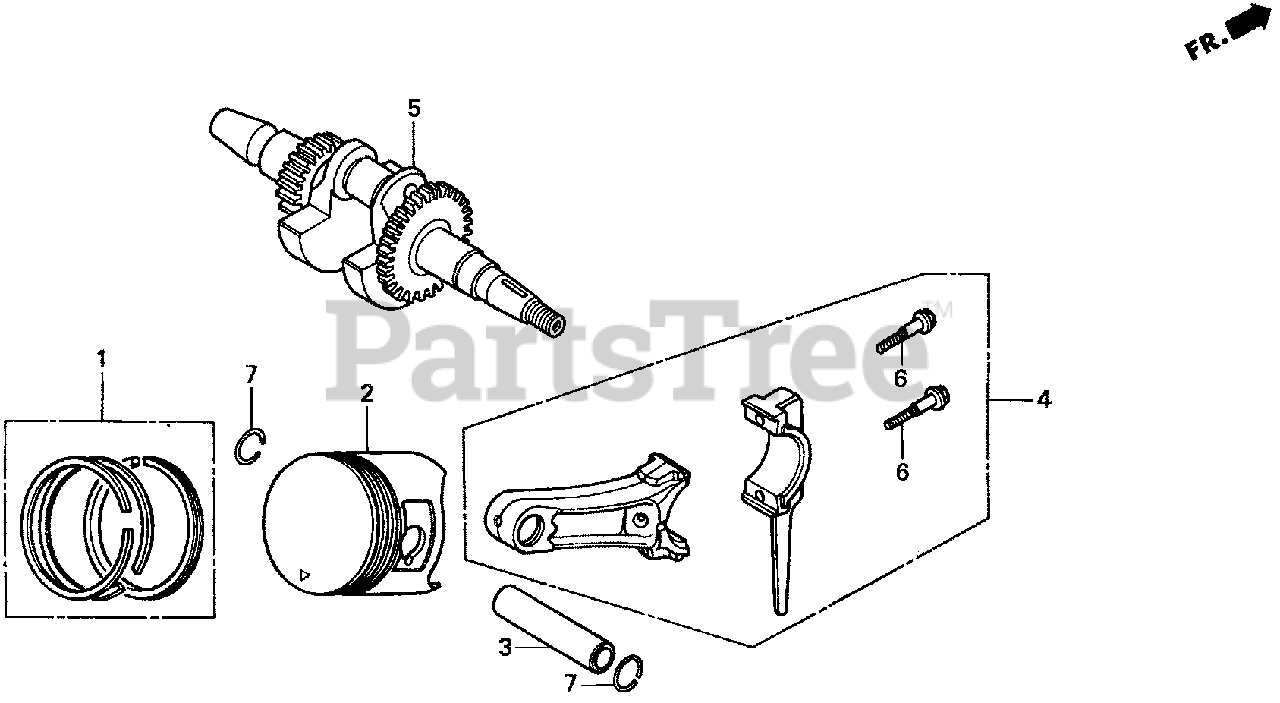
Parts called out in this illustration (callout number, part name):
1	RING SET, PISTON (STD)
1	RING SET, PISTON (STD) (TEIKOKU)
1	RING SET, PISTON (STD) (NIPPON)
1	RING SET, PISTON (OS 0.25) Use up to Engine SN 3993725.
1	RING SET, PISTON (OS 0.25) Use from Engine SN 3993726.
1	RING SET, PISTON (OS 0.50) Use up to Engine SN 3993725.
1	RING SET, PISTON (OS 0.50) Use from Engine SN 3993726.
1	RING SET, PISTON (0.75) Use up to Engine SN 3993725.
1	RING SET, PISTON (0.75) Use from Engine SN 3993726.
2	PISTON (STD)
2	PISTON (OS 0.25) Use up to Engine SN 3993725.
2	PISTON (OS 0.25) Use from Engine SN 3993726.
2	PISTON (OS 0.50) Use up to Engine SN 3993725.
2	PISTON (OS 0.50) Use from Engine SN 3993726.
2	PISTON (0.75) Use up to Engine SN 3993725.
2	PISTON (0.75) Use from Engine SN 3993726.
3	PIN, PISTON
4	ROD ASSY., CONNECTING
5	CRANKSHAFT (VE-TYPE)
6	BOLT, CONNECTING ROD
7	CLIP, PISTON PIN (13MM)
